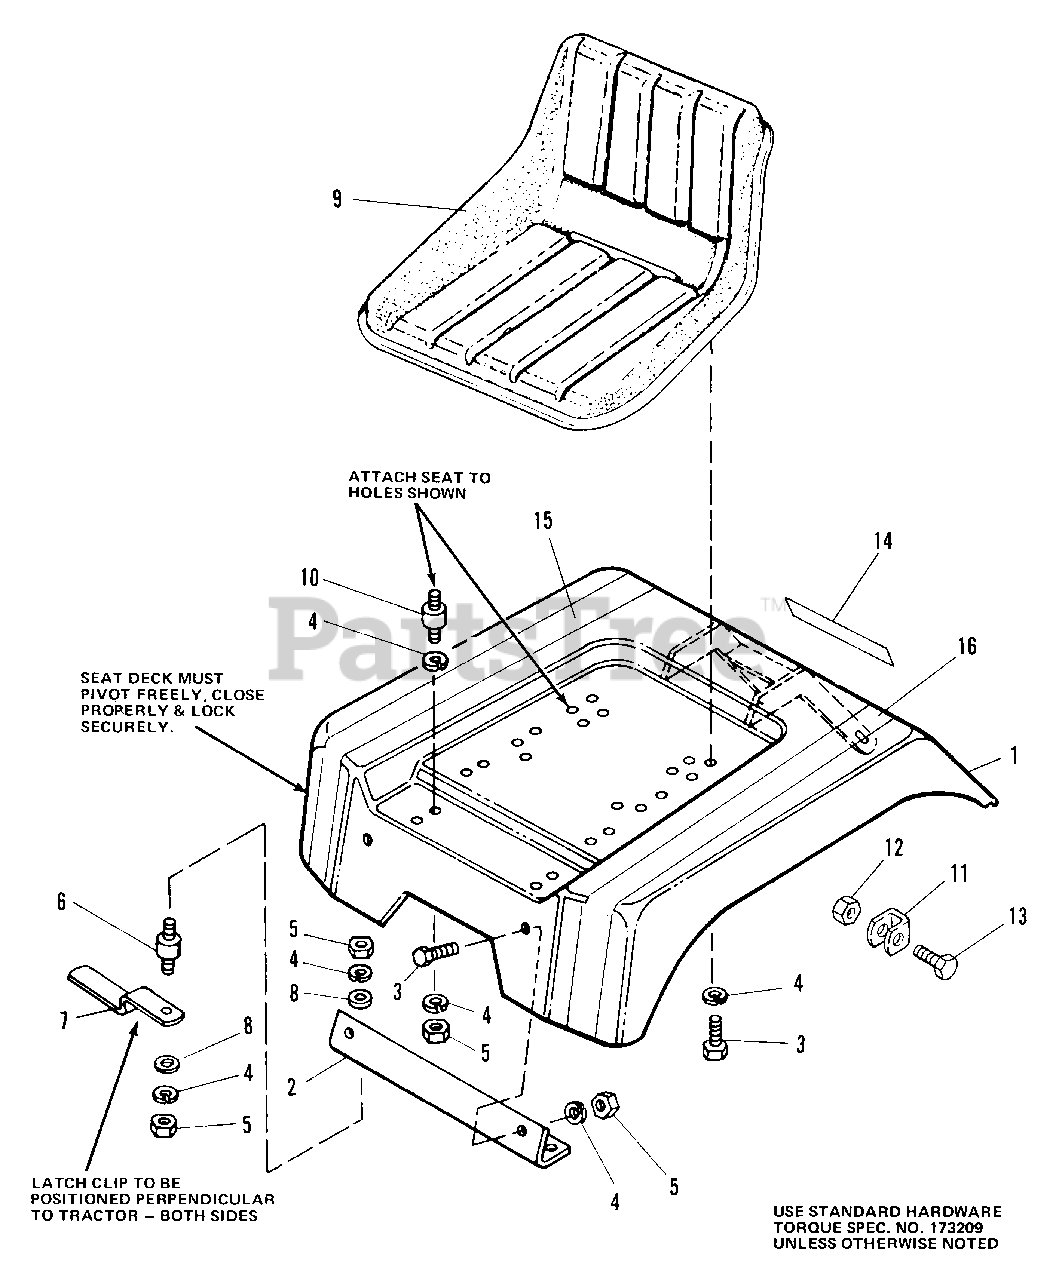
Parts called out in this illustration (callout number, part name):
1	SEAT, Deck
2	BRACKET, Frt. Seat Deck
3	CAPSCREW, 5/16-18 x 5/8
4	LOCKWASHER, 5/16
5	NUT, Hex, Full, 5/16-18
6	CONNECTOR, Cushion
8	WASHER, 1/4
10	CONNECTOR, Cushion
11	STOP, Seat Deck
12	LOCKNUT, Hex, 3/8-16
13	CAPSCREW, Hex, 3/8-16 x 1-1/4
14	DECAL, Simplicity
15	DECAL, Strip R.H.
16	DECAL, Strip L.H.
